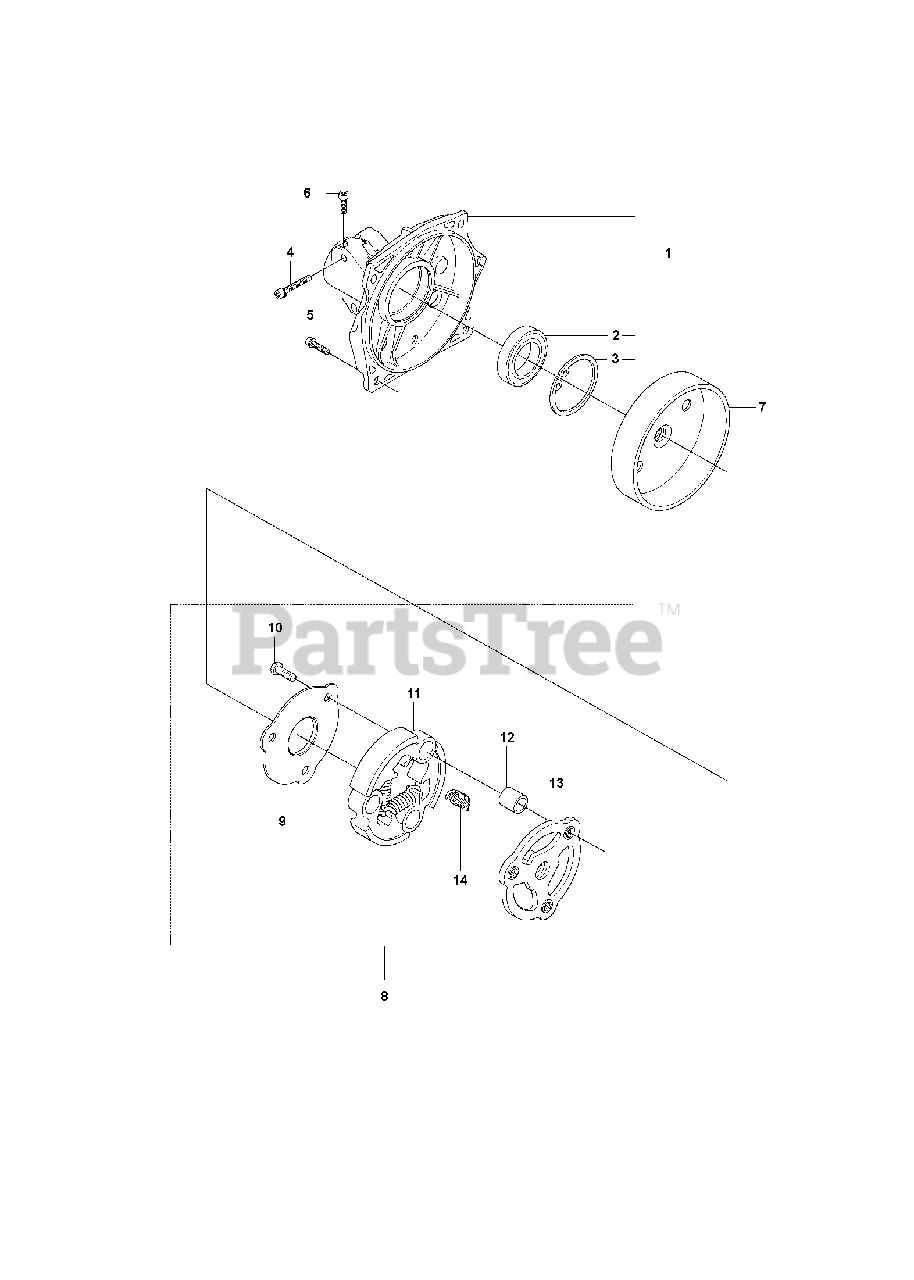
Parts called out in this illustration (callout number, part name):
1	CLUTCH COVER
2	BALL BEARING 6202-2RS1
3	RETAINING RING SGH 35
6	SCREW MC6LS 5X12
7	CLUTCH DRUM ASSM.
8	CLUTCH CPL
9	WASHER
10	SCREW
11	CLUTCH
12	BUSHING
13	HUB
14	CLUTCH SPRING
